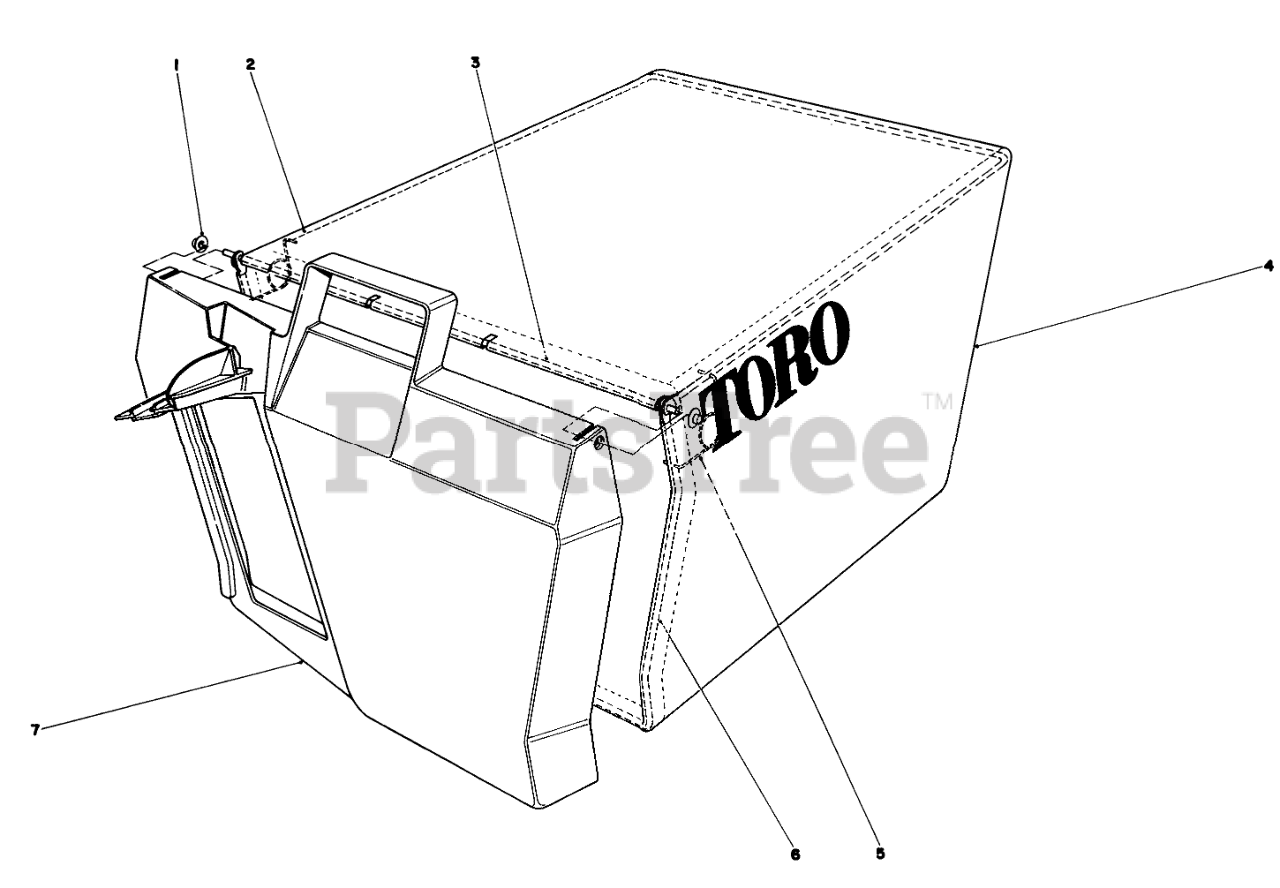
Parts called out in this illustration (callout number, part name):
1	NUT-PUSH
2	Bag Frame Upper
3	HINGE-DOOR, BAG
4	Grass Bag
5	SPRING
6	Frame Bag
7	Door Grass Bag
